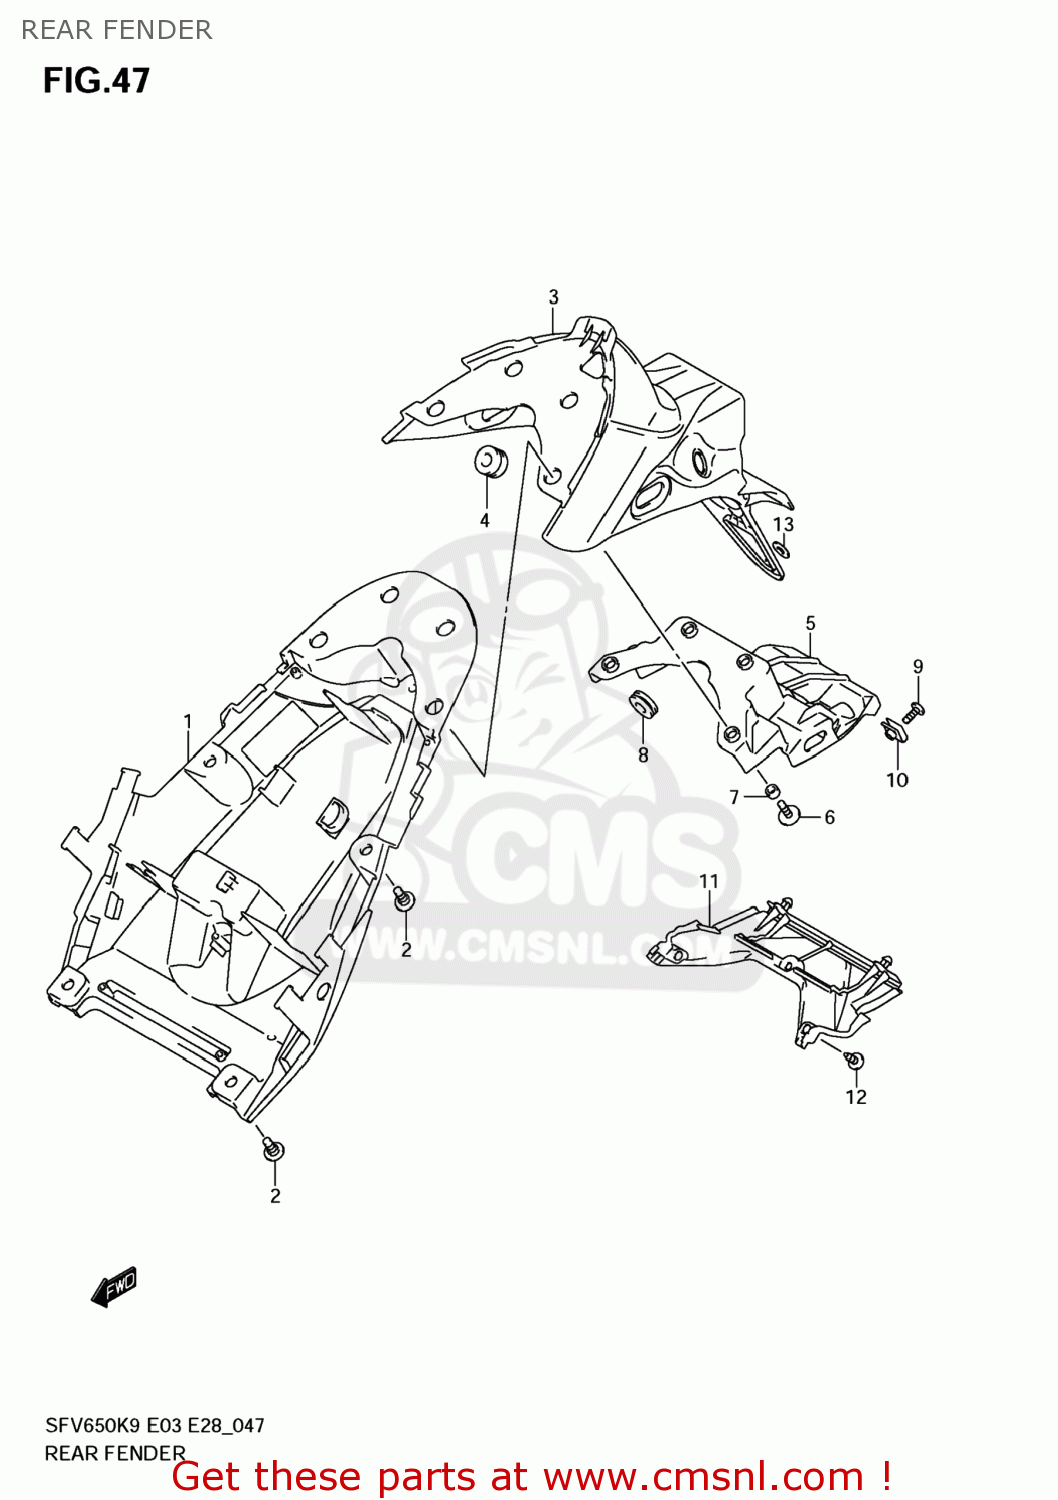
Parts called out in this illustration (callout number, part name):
1	FENDER,RR FR
2	BOLT
3	FENDER,RR RR
4	CUSHION(30X50X3)
5	BRACKET,RR FENDER RR
6	BOLT(6X20)
7	SPACER(6.1X9X7.5)
8	CUSHION
9	SCREW
10	NUT
11	COVER,RR FENDER RR
12	SCREW
13	WASHER(6.5X20X1.2)
